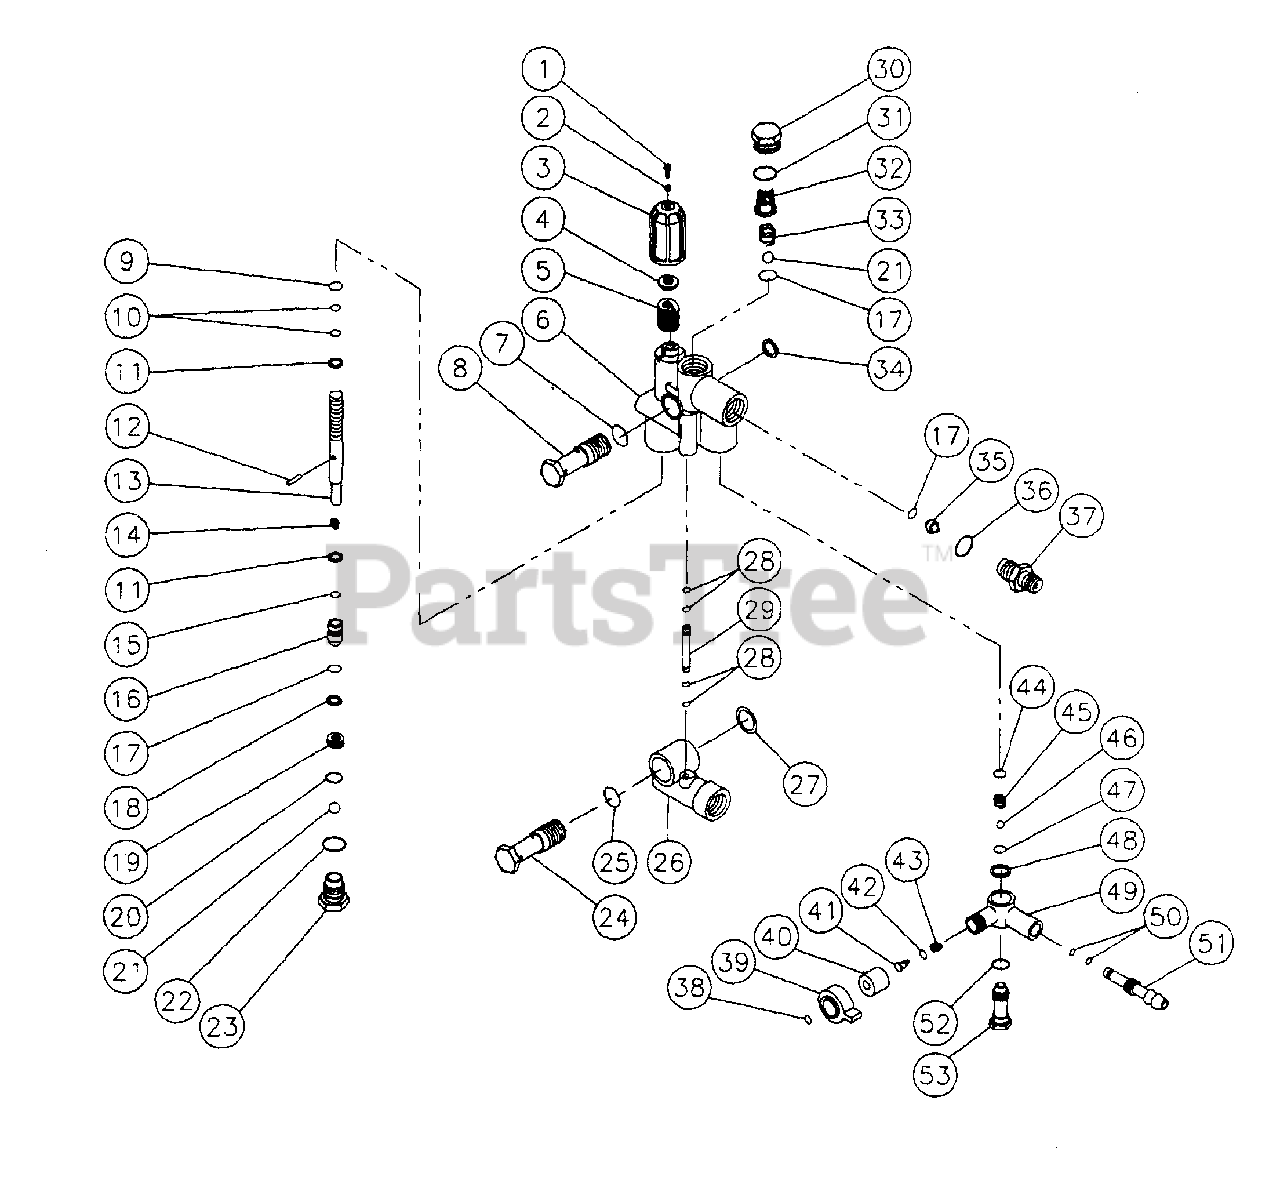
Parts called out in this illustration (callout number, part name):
3	Pressure Regulating Knob
4	Spring Guide
6	Valve Body-Brass
8	Fixing Screw-Brass
9	Anti-Extension Ring
13	Piston Guide
16	Drive Piston
18	Back-up Ring
19	Valve Seat
23	Cap-Brass
24	Fixing Screw
26	Inlet Body
29	By-pass Tube
32	Valve Guide
38	Snap Ring
39	Injector Regulating Knob
40	Knob Insert
49	Injector Body
51	Hose Barb
53	Valve Seat
